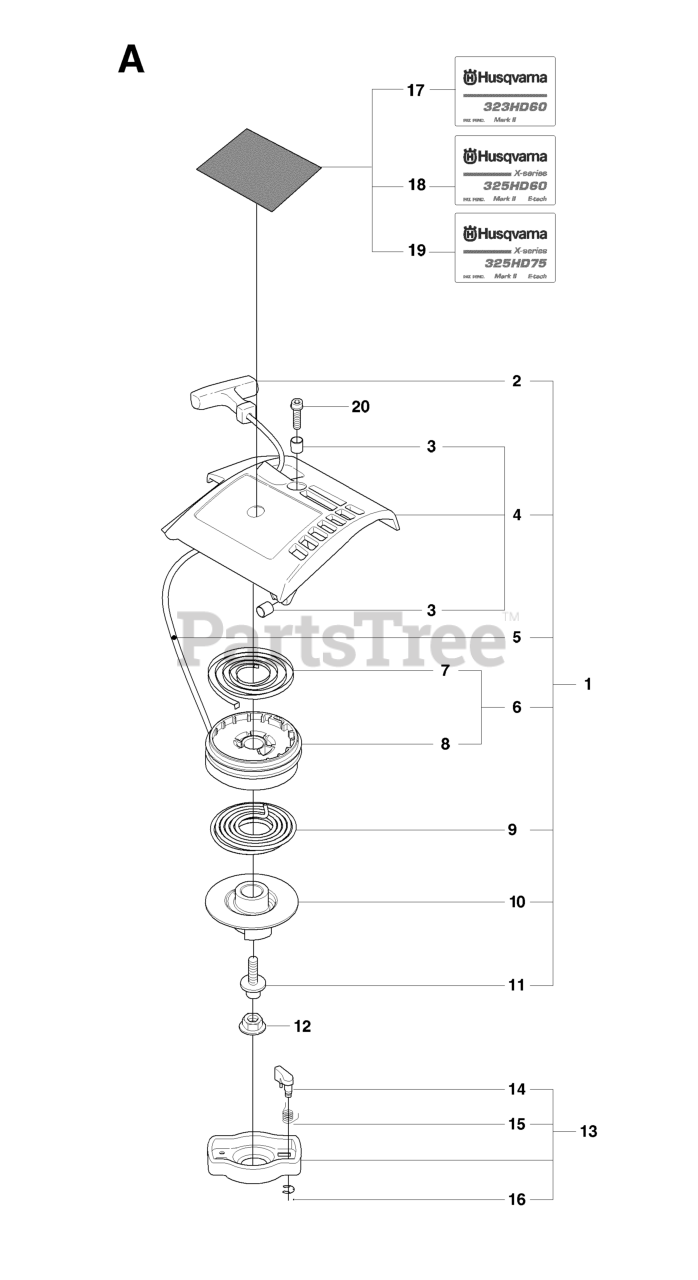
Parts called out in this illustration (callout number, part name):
1	RP STARTER ASSY
2	STARTER HANDLE
3	SPACING SLEEVE
4	STARTER HOUSING
5	STARTER ROPE
6	STARTER PULLEY
8	STARTER PULLEY
9	SPRING - DRIVER
10	DRIVER PULLEY
12	FLANGE NUT
13	PAWL ASSY COMPLETE
14	STARTER PAWL
